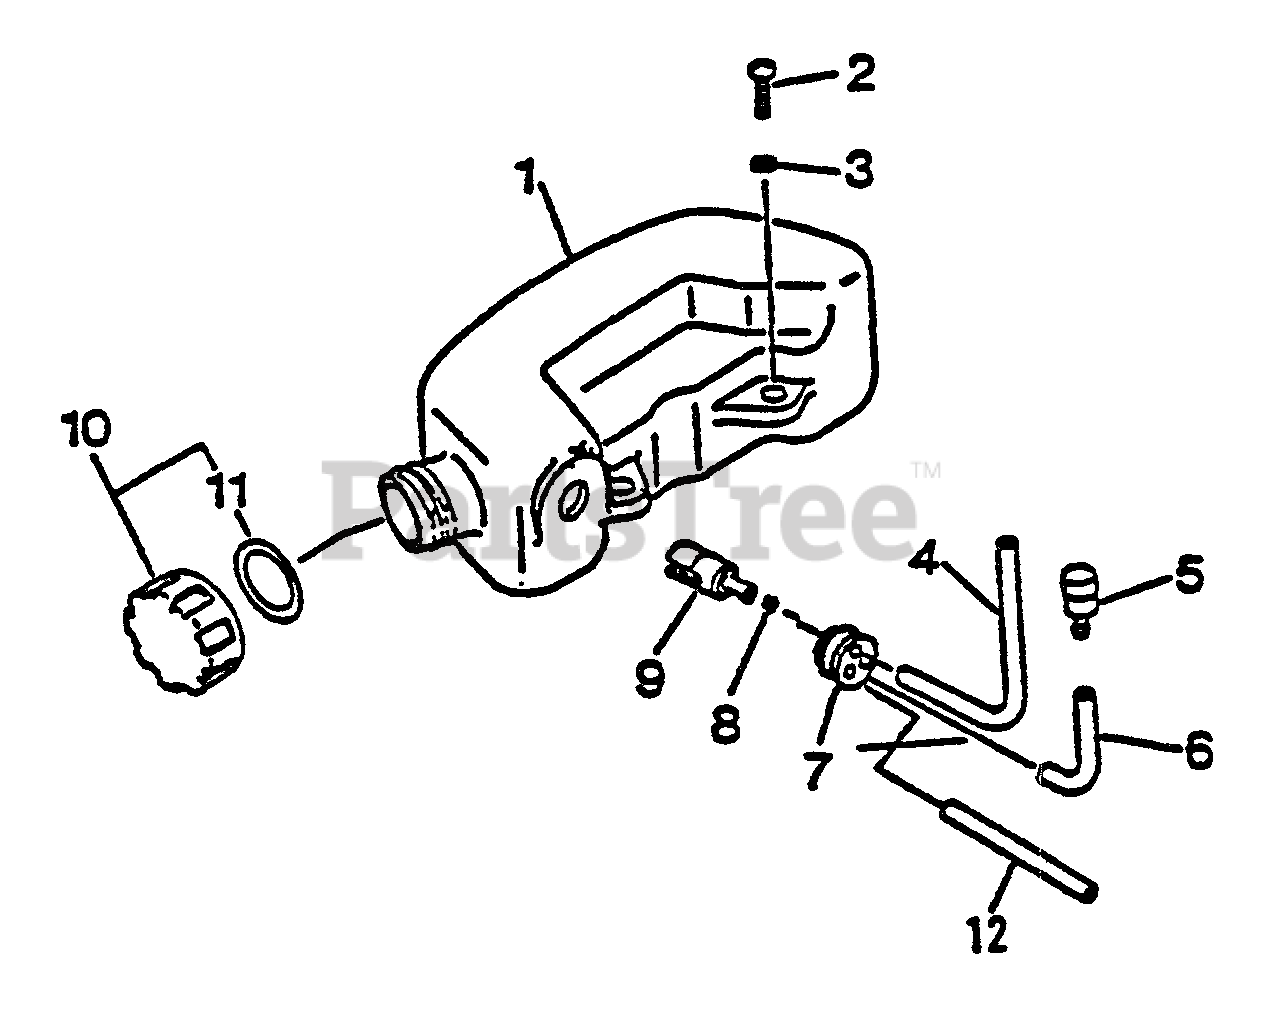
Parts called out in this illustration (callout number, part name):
1	TANK, FUEL
2	SCREW 5×16
3	WASHER 5.5×12×0.8
4	PIPE, FUEL
5	VENT ASSY
6	PIPE, FUEL RETURN 3×6×70
7	GROMMET, FUEL
8	CLIP 6 MM
9	FILTER, FUEL
10	CAP ASSY
11	GASKET, FUEL CAP
12	PIPE, FUEL RETURN 3×6×110
